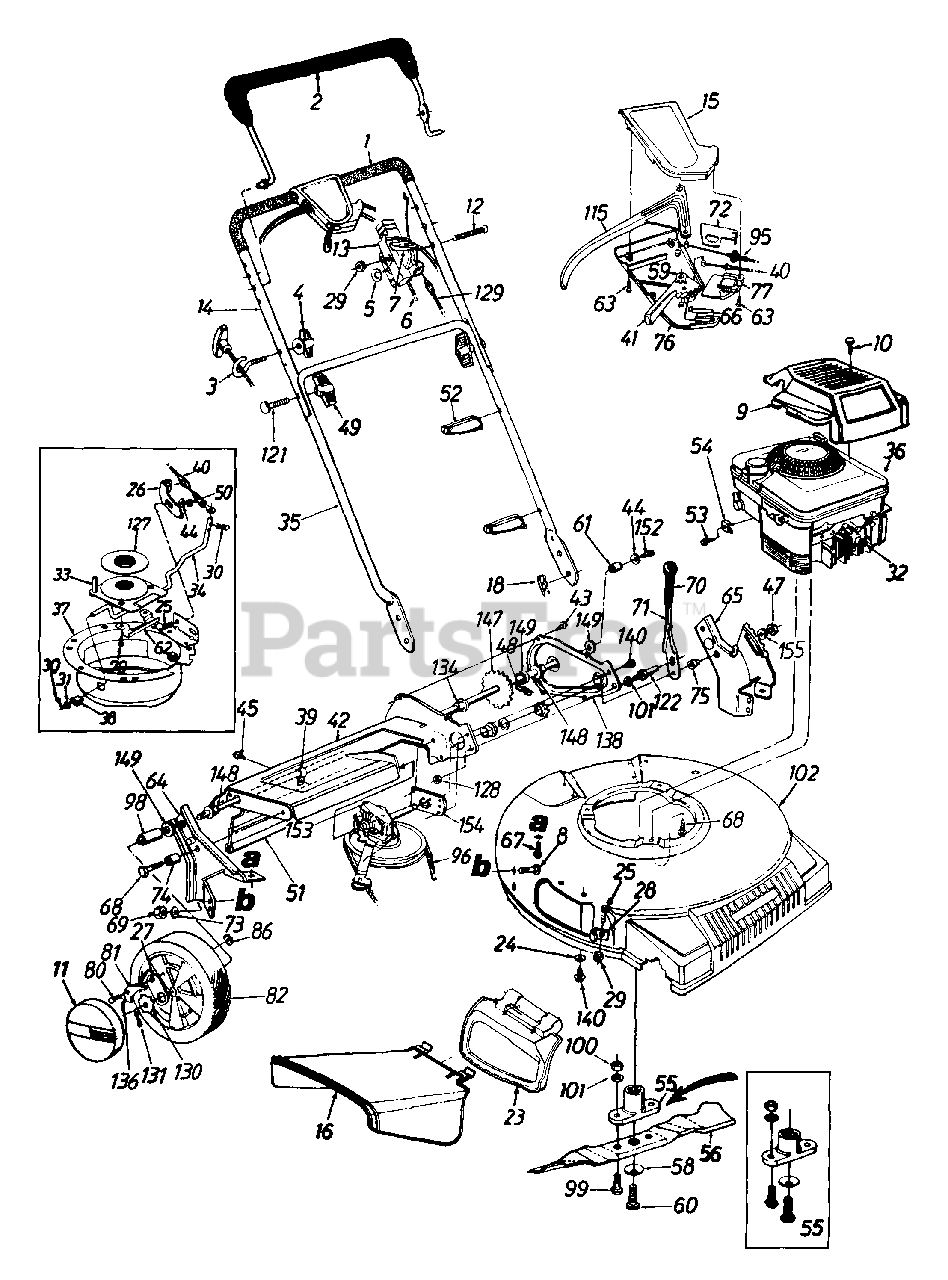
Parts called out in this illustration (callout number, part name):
1	Foam Grip
2	Control Handle
4	Handle Knob 1/4-20 Thd.
5	Curved Spring Wash. .66" I.D.
6	Throttle Wire - 55" Lg.
7	Throttle Lever
8	Carriage Bolt 5/16-18 x .62" Lg.
9	XTE Engine Shroud
10	Hi-Lo Screw #10 x 1.25" Lg.
11	Hub Cap
12	Oval C-Sunk Mach. Scr.
13	Throttle Body
15	Upper Control Housing
16	Side Chute Deflector
18	Internal Cotter Pin 5/16" Dia.
23	Mulch Plug Ass'y. Comp.
24	Bell-Wash. .265" I.D. x .75" O.D.
25	Carriage Bolt 1/4-20 x .5" Lg.
30	Cotter Pin 3/32" Dia. x .75"
31	Fl-Wash. .328" I.D. x .68"
32	Spark Plug Insulator
33	Pulley Ass'y.
36	Engine - 5.5 H.P.
40	6 Spd. Cable
41	6 Spd. Shift Lever
44	Bell-Wash. 1/4" I.D.
47	Hex Patch L-Nut 3/8-24 Thd.
48	#48 Chain .500" Pitch x 38 Links
49	Hand Knob
50	Hex L-Nut 1/4-20 Thd.
51	Rear Flap 4.8" x 17.5" Lg.
52	Cable Tie
53	Hex Wash. Hd. Scr. #10-32 x .62" Lg.
54	Casing Clamp
55	Kit - Blade Adapter Kit Keyed
56	21" Mulching Blade
58	Bell-Wash. .39" I.D. x 1.14" O.D.
59	Gear Insert
60	Hex Bolt 3/8-24 x 2.5" Lg. (Gr. 8)
61	Spacer .513" I.D.
67	Hex B-Tap Scr. 5/16-18
68	Hex TT-Tap Scr. 3/8-16
69	Hex Nut 5/16-18 Thd.
71	Height Adj. Lever
72	6 Spd. Rack Cable Brkt.
73	Bell-Wash. 5/16" I.D.
74	Spacer .383" I.D.
75	Shld. Spacer .5" Dia.
76	Lower Control Housing
77	Cable Mounting Cap
78	Wave Wash. .88" I.D. x 1.38" O.D.
80	Shld. Scr. .342" Dia. x .268
81	Pawl - R.H.
82	Wheel Ass'y. Comp.
86	Weld Top L-Nut 1/4-20 Thd.
95	S.P. Cable
96	"V" - Belt
98	Sleeve .526" I.D.
99	Hex Bolt 3/8-24 x 1.0" Lg.
100	Hex Nut 3/8-24 Thd.
101	L-Wash. 3/8" I.D.
121	Curved Hd. Bolt 5/16-18 x 2" Lg.
122	Shld. Pin 1.43" Lg.
128	Hex Jam Nut 3/8-24 Thd.
129	Control Cable - 39"
130	Ratchet Wheel 1.62" O.D.
131	Cotter Pin 1/8" Dia. x 1"
134	Hex Flange Bearing
136	Spring - Nylon
147	Rear Shaft Ass'y. 21.44" Lg.
148	Hex Flange Brg. .506" I.D.
149	Fl-Wash. .531" I.D. x .930"
152	Hex Bolt 1/4-20 x .62" Lg. (Gr. 5)
153	Transmission Comp.
155	Fl-Wash. .385" I.D. x .87" O.D.
7530609	Kit - Blade Adapter Kit Keyed
